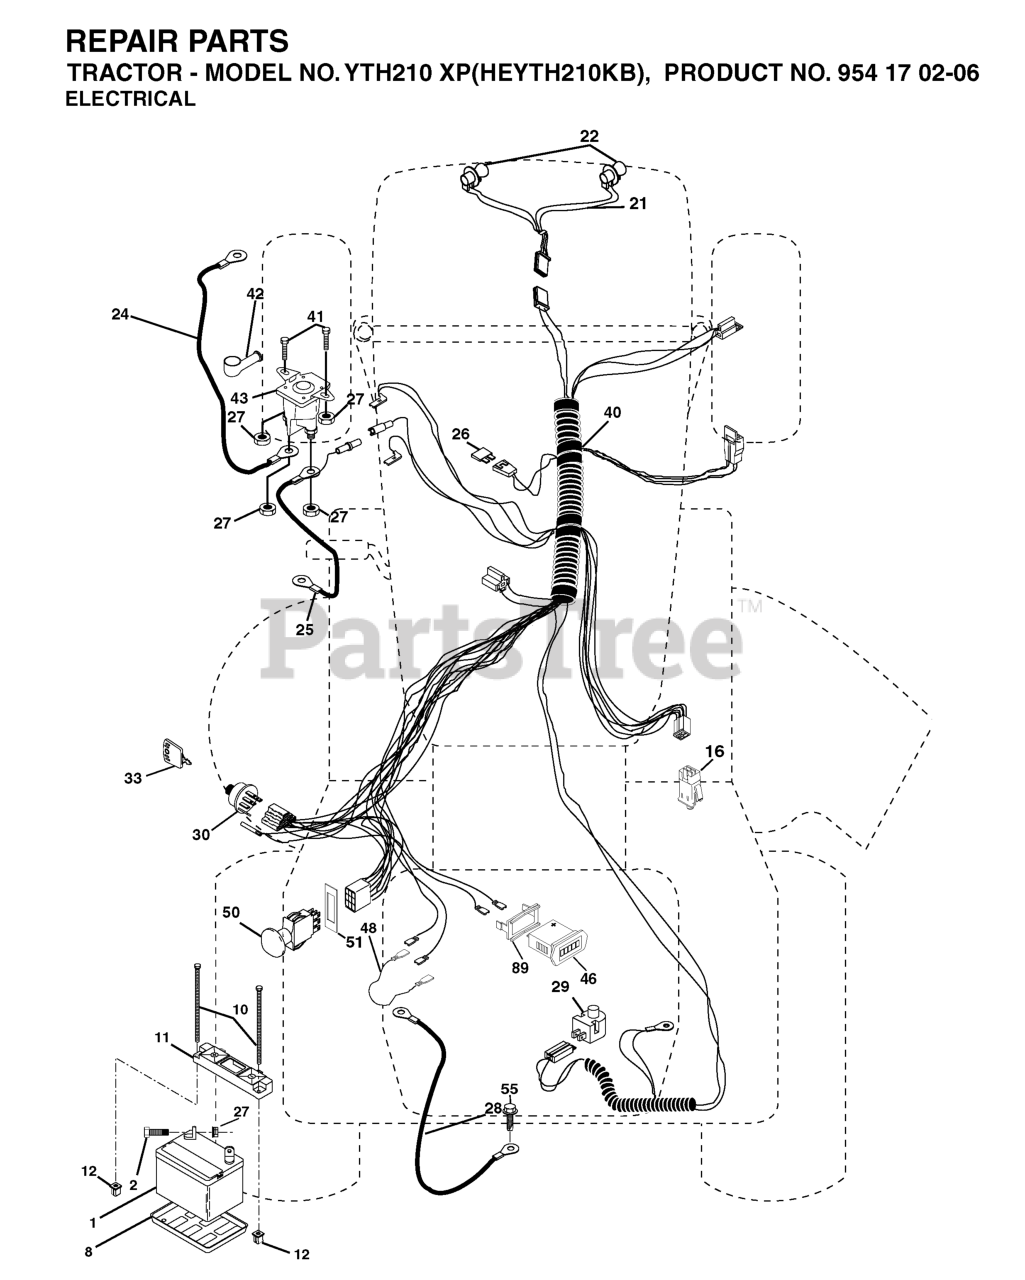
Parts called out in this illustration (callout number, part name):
1	BATTERY 12V .35 AMP
2	BOLT.HEX.1/4.X.3/4.DICHROMATE
8	BATTERY TRAY T
10	BOLT 1/4-20 X 7.5
11	BATTERY HOLDDOWN FRONT MOUNT
12	NUT, PUSH NYLON 1/4" BATTERY
16	SWITCH INTERLOOK PUSH-IN
21	HARNESS.W/LIGHT SOCKET
24	BATTERY CABLE GT
25	CABLE BATTERY 6 GA 22" W/16W
26	FUSE 20AMP
27	NUT
28	CABLE GROUND 6 GA 21" 90T BLK
29	RP.SWITCH.PLUNGER.NC.GRAY
30	IGNITION SWITCH
33	KEY MLD GEN DELTA
40	HARNESS.IGNITION
41	BOLT
42	TERMINAL COVER
43	SOLENOID
46	HOUR METER
48	ADAPTER.AMMETER
50	RP.PTO.SWITCH.8 TERMINAL.BLACK
51	FRAME RETAINING RING
55	Screw 5/16-18 x 1/2 Hex, Self Tapping 5/16-18 x 1/2
89	BRACKET SNAP-IN HOURMETER
